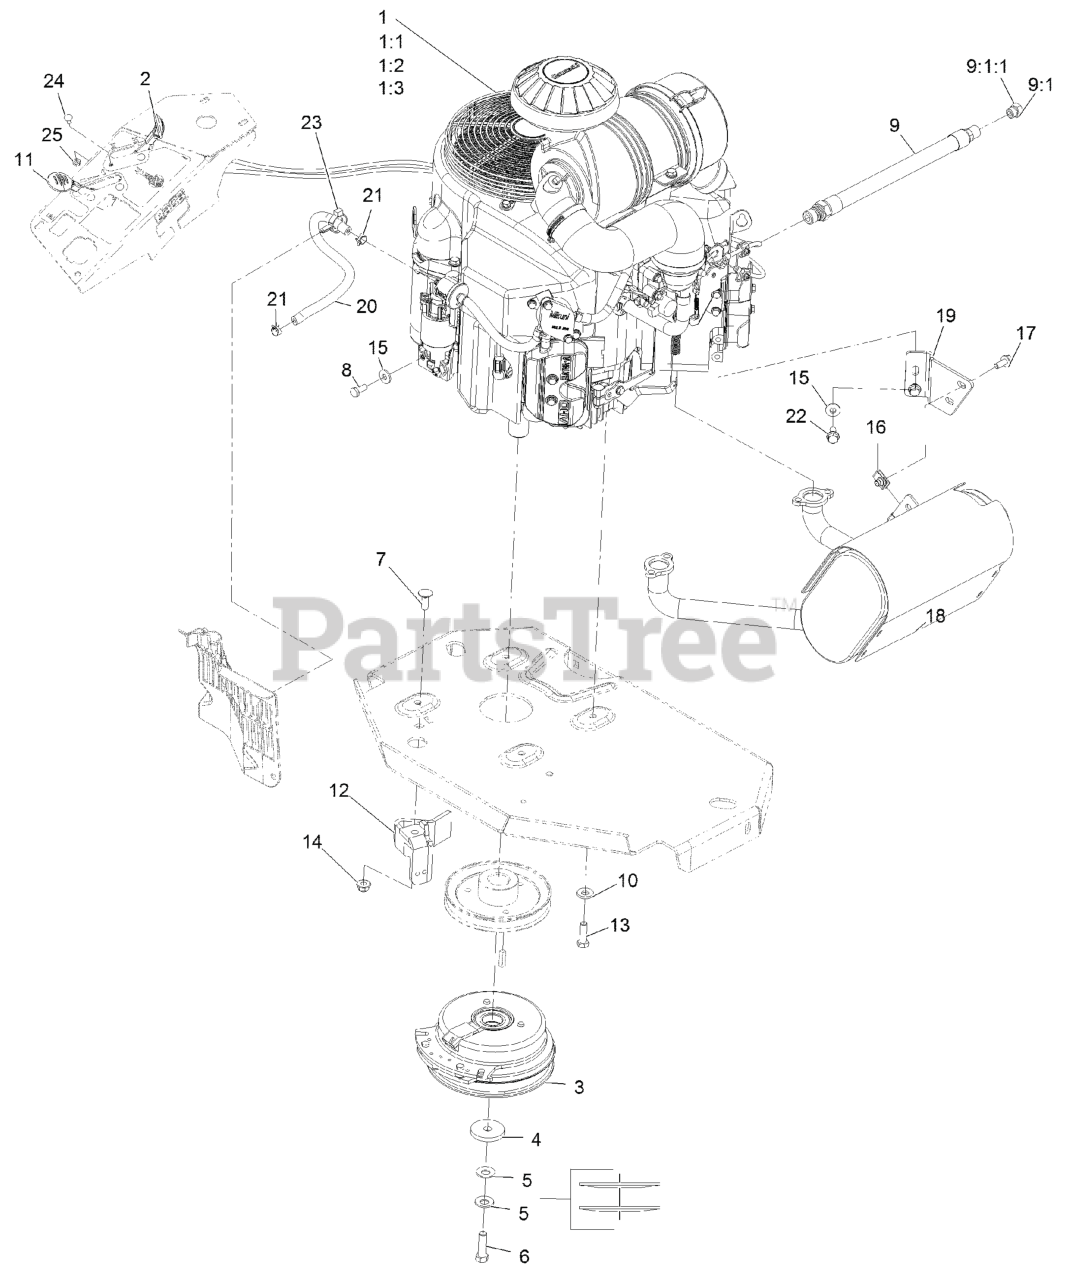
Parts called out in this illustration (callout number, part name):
1:1	Kawasaki 49065-2078 Engine Oil Filter
1:2	Kawasaki 11013-7044 Engine Air Filter
1:3	Kawasaki 11013-7045 Safety Filter
2	ASM, CHOKE CABLE
3	CLUTCH KIT
4	WASHER-CLUTCH
5	WASHER-SPRING
6	SCREW-HH 7/16-20 X 1 1/2 W/LOCTITE
7	SCREW-CARR
8	SCREW-HH
9	ENGINE OIL DRAIN HOSE ASM
9:1	PLUG-HH
9:1:1	O-RING
10	WASHER-BELLEVILLE
11	ASM,THROTTLE CABLE
12	CLUTCH-ANCHOR
13	SCREW-HH
14	NUT-HF, NI
15	WASHER-SPRING
17	SCREW-HHF
18	MUFFLER
19	BRACKET-MUFFLER
20	HOSE-FUEL
21	CLAMP-HOSE
22	SCREW-HHF
23	CLAMP-HOSE
24	BOLT-CARR
25	NUT-LOCK, NI
